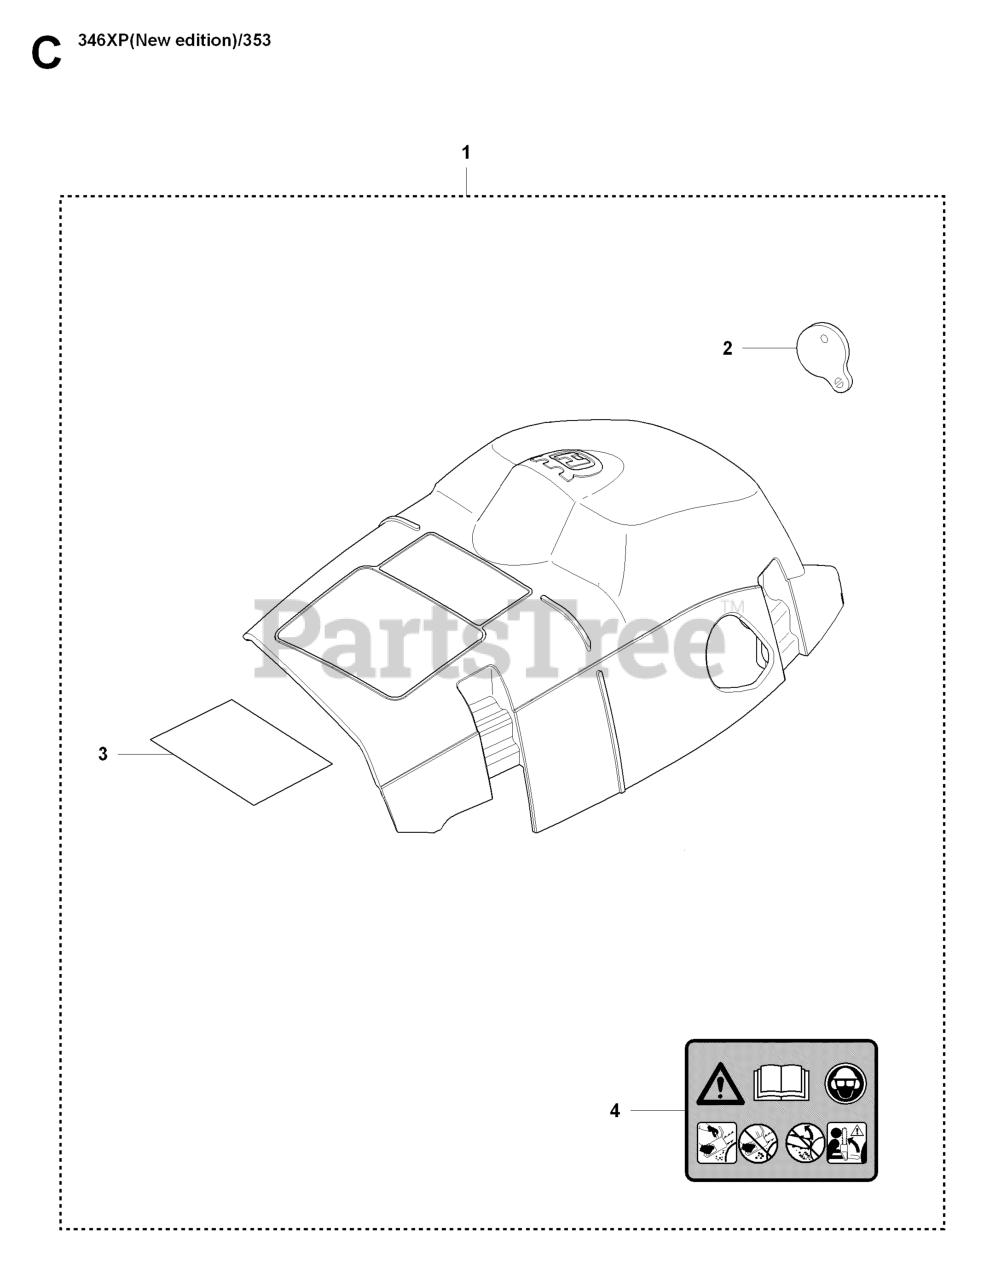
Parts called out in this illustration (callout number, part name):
1	CYLINDER COVER ASSY
2	COVER
3	INSULATING FOIL/CYLINDER COVER
